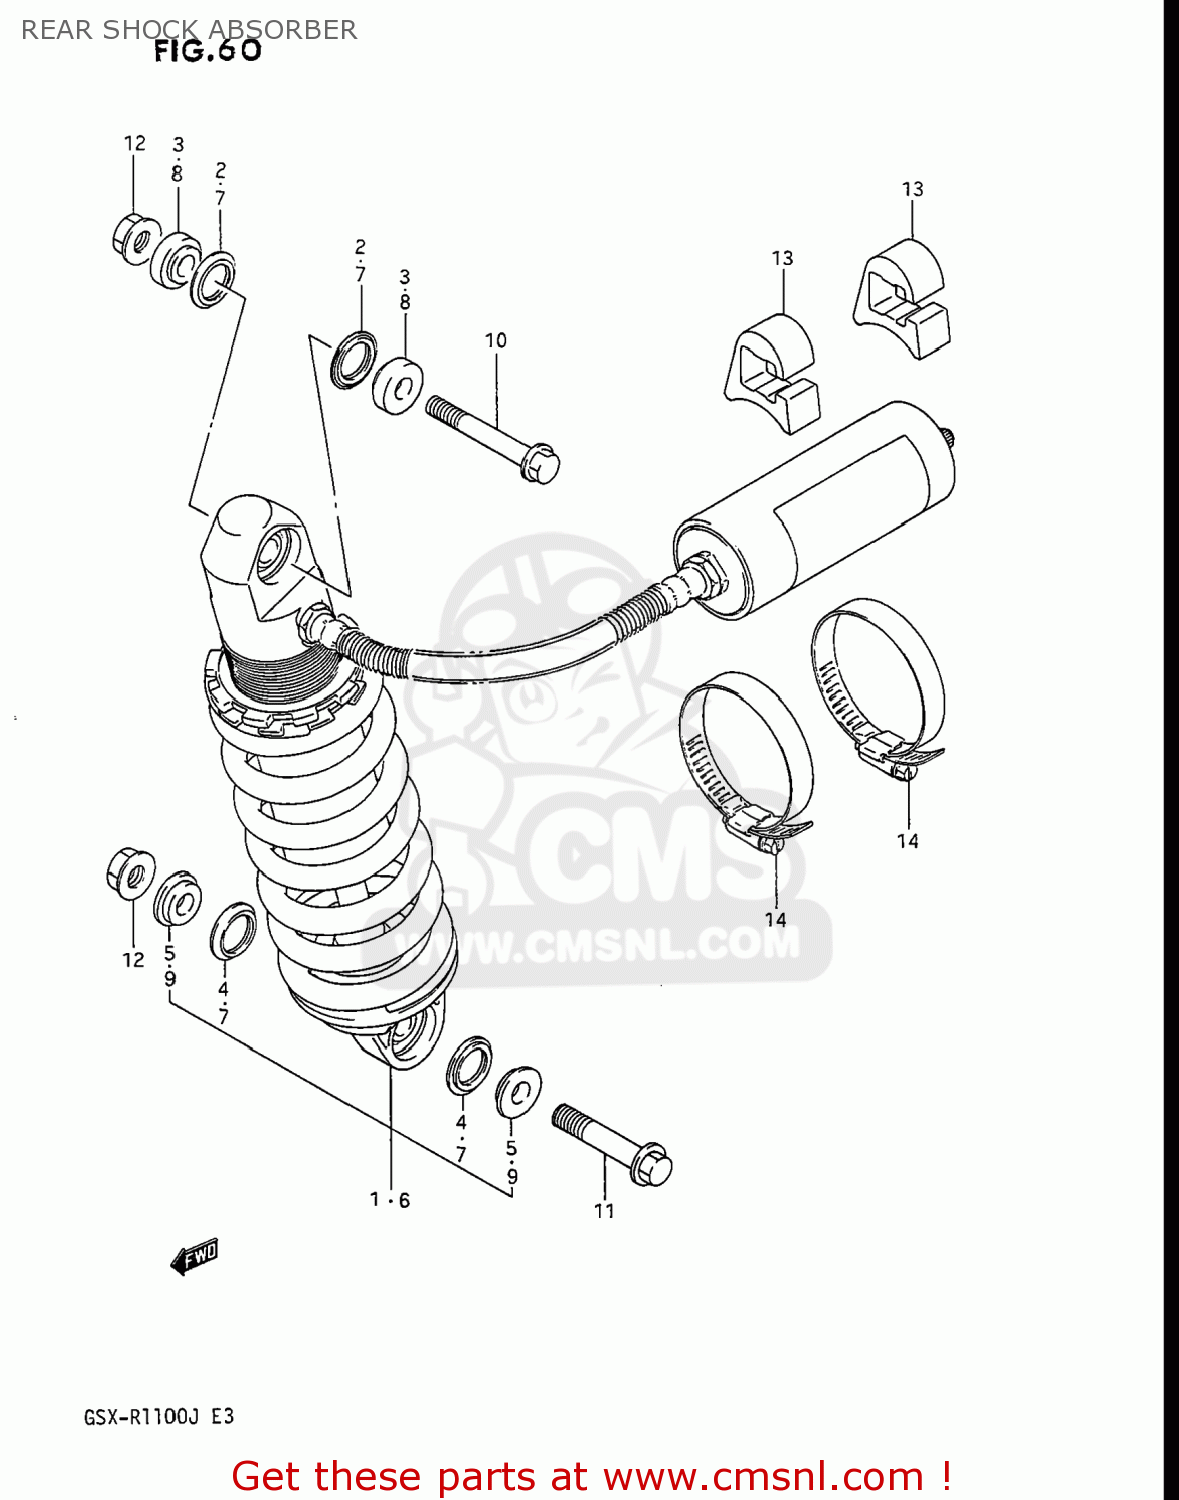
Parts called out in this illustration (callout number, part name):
1	ABSORBER ASSEMBLY,REAR SHOCK
2	SEAL,DUST RR SHOCK ABSORBER
3	COLLAR
4	O-RING,FORK INNER TUBE
5	SPACER,REAR SHOCK,UPPER
6	ABSORBER ASSEMBLY,REAR SHOCK
7	SEAL DUST
8	COLLAR
9	COLLAR
10	BOLT
11	BOLT(10X48)
12	NUT
13	CUSHION,RESERVOIR TANK
14	CLAMP
